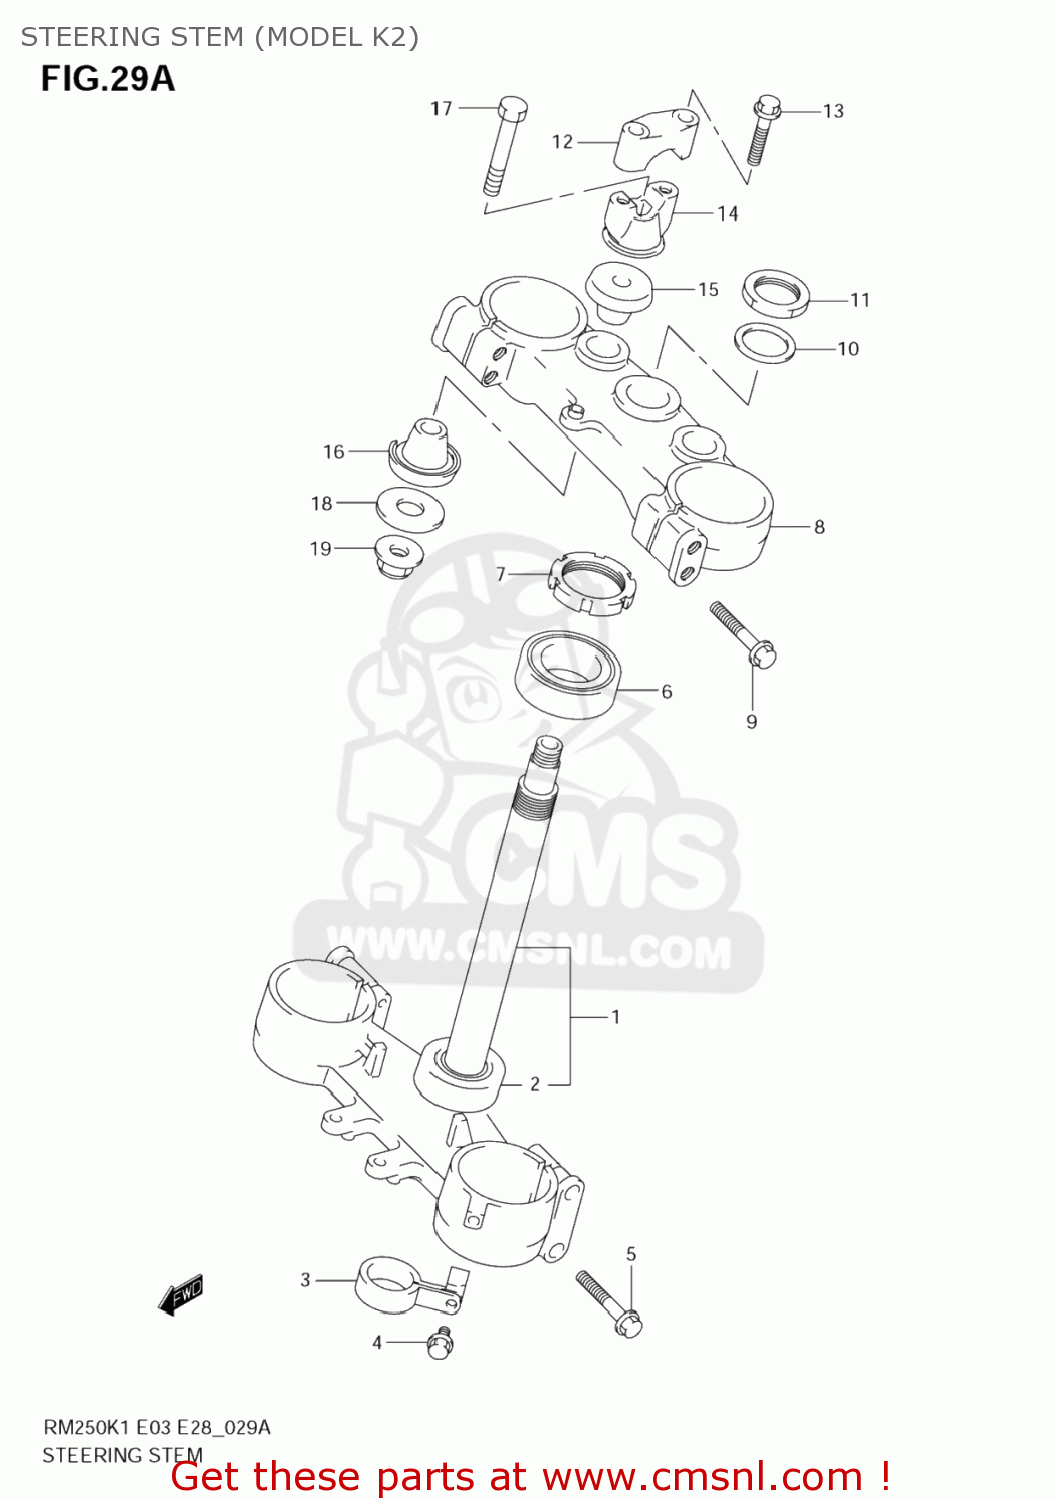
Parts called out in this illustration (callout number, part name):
1	STEM,STEERING
2	BEARING(30X52X16)
3	GUIDE,FR BRAKE HOSE
4	BOLT
5	BOLT
6	BEARING(30X52X16)
7	NUT,STEERING
8	HEAD,STEERING STEM
9	BOLT
10	WASHER,STEM HEAD(24.5X34X1.6)
11	NUT
12	HOLDER,HANDLE
13	BOLT
14	HOLDER,HANDLE LWR
15	DAMPER,UPR
16	DAMPER,LWR
17	BOLT
18	WASHER(10.5X28X2.3)
19	NUT
